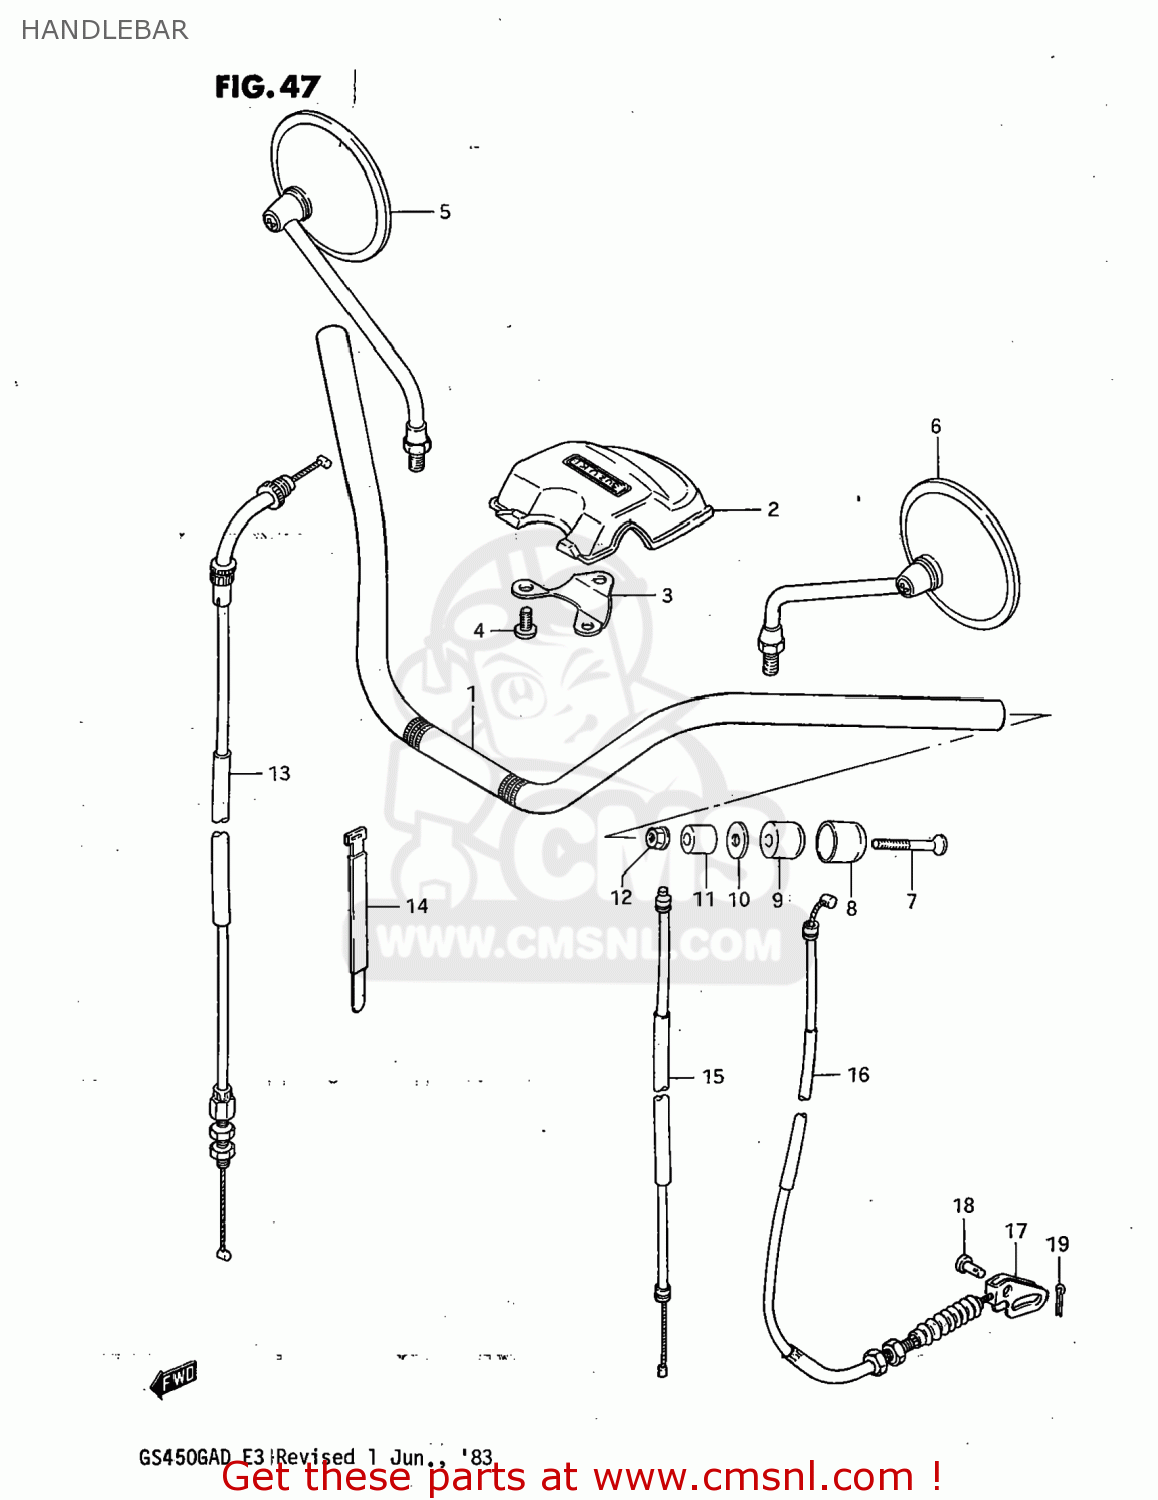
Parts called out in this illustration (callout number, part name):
1	HANDLEBAR
2	COVER,STEERING HEAD
3	BRACKET,HEAD COVER
4	SCREW
5	MIRROR ASSEMBLY,RIGHT
6	MIRROR ASSEMBLY,LEFT
7	SCREW
8	CAP,BALANCER
9	BALANCER,HANDLEBAR
10	SPACER,BALANCER
11	EXPANDER,HANDLE BALANCER
12	NUT
13	CABLE ASSEMBLY,THROTTLE
14	CLAMP
15	CABLE ASSEMBLY,STARTER
16	CABLE ASSEMBLY,PARKING BRAKE
18	PIN(L:15)
19	PIN
